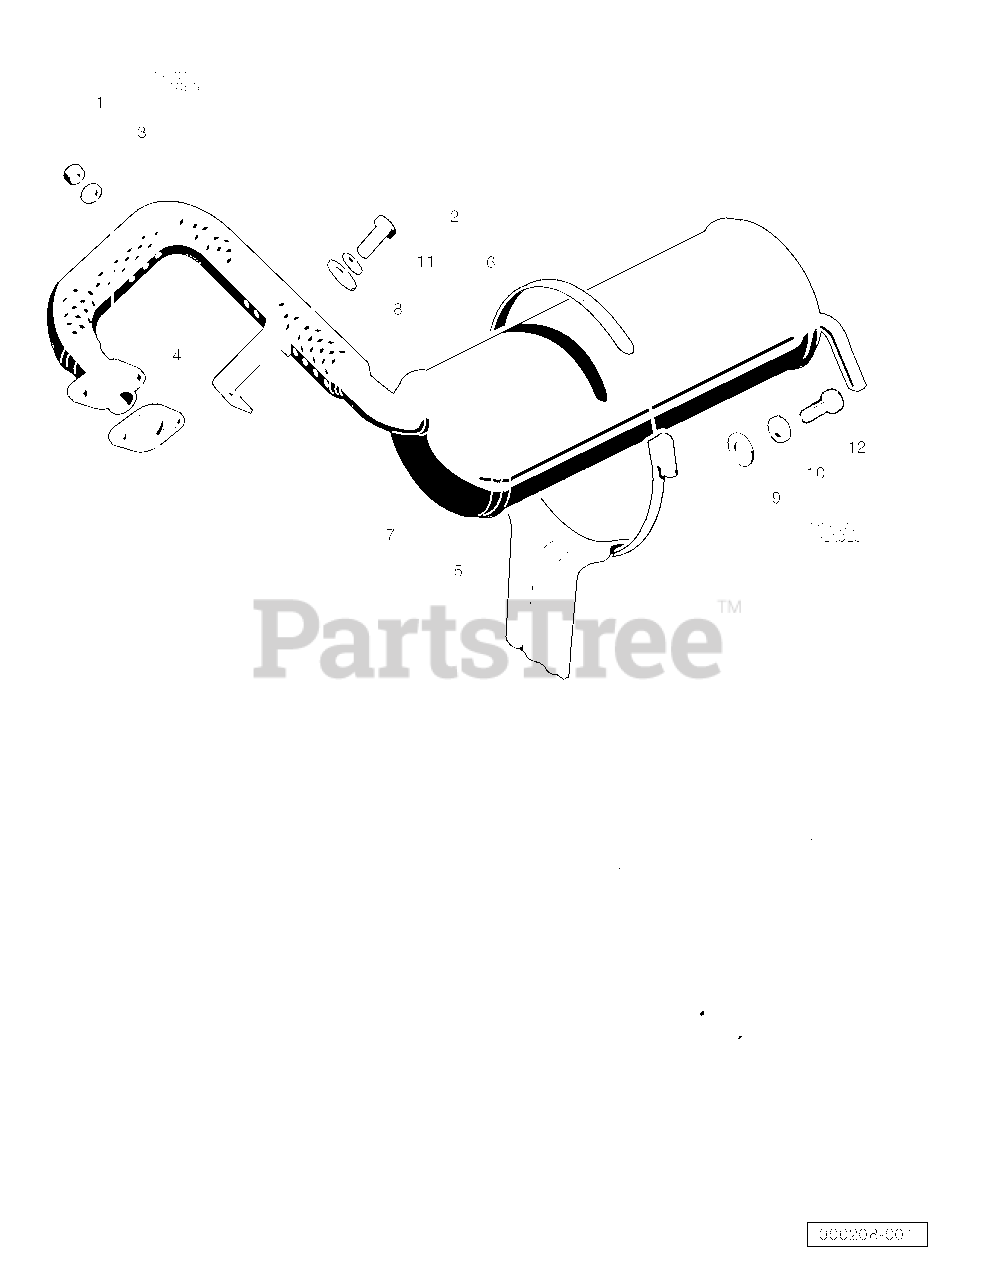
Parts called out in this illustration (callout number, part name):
1	Nut, M8-1.25 Hex
2	Screw, M8-125 X 22 Hex-Head
3	Lockwasher, 8mm Split
4	Gasket, Exhaust
5	Bracket, Muffler Mounting
6	Clamp, 5" Muffler Hose
7	Exhaust System, FE290
8	Washer, 5/16 Type A Flat
9	Washer, 1/4 Type A Narrow Flat
10	Lockwasher, 1/4 Helical Split
11	Lockwasher, 5/16 Split
12	Screw, 1/4-20 X 0.75 Hex-Head Cap
